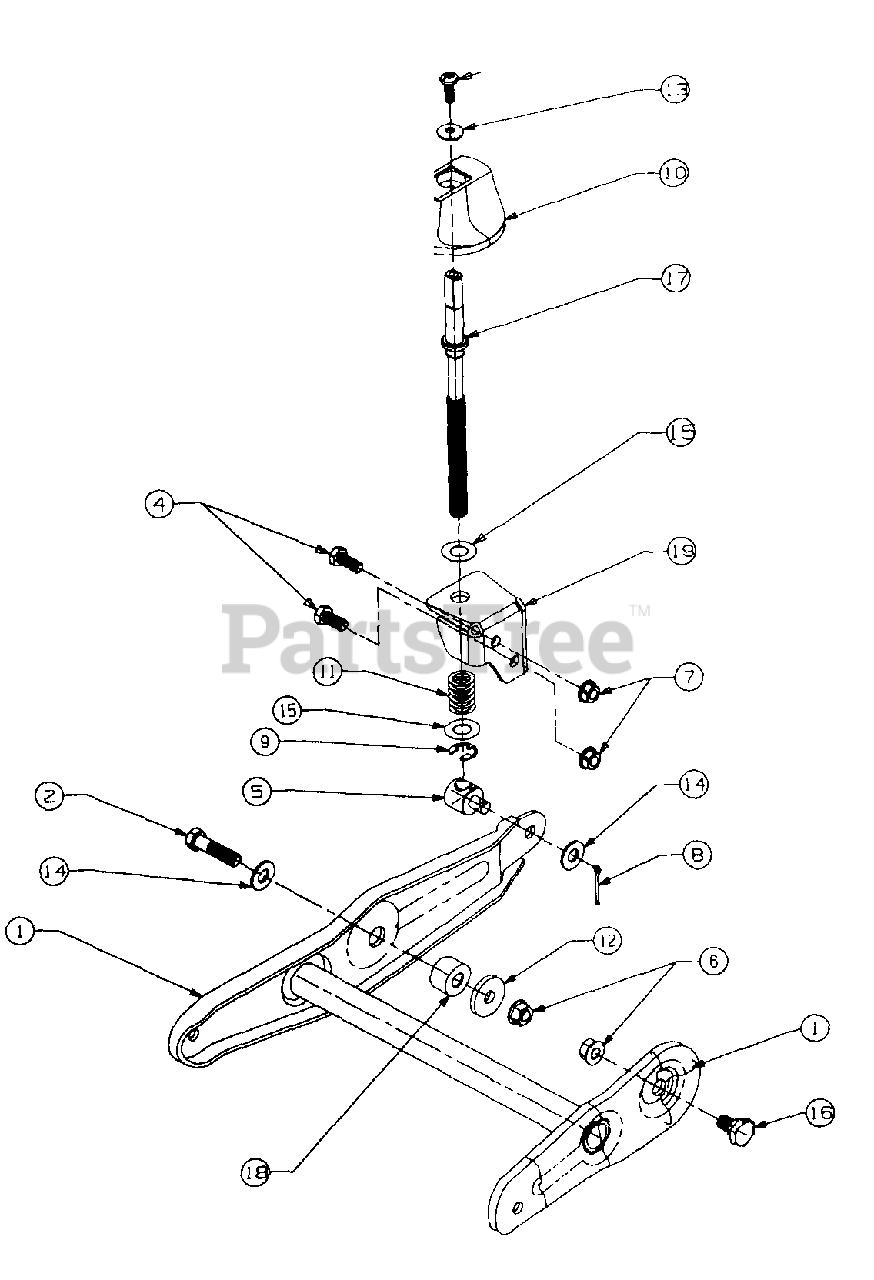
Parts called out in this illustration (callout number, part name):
3	SCREW-MACHINE PAN HD
4	SCREW-HEX
5	FERRULE - ADJUSTABLE
6	NUT-HEX FLANGE LOCK
7	NUT-HEX FLANGE
8	PIN-COTTER
9	RING-E
10	KNOB-PLASTIC
11	SPRING-COMPRESSION
12	WASHER-FLAT
13	WASHER-BELL
14	WASHER-FLAT
15	WASHER-FLAT
16	SCREW-SHOULDER
17	ROD-ADJUSTABLE
18	SPACER
